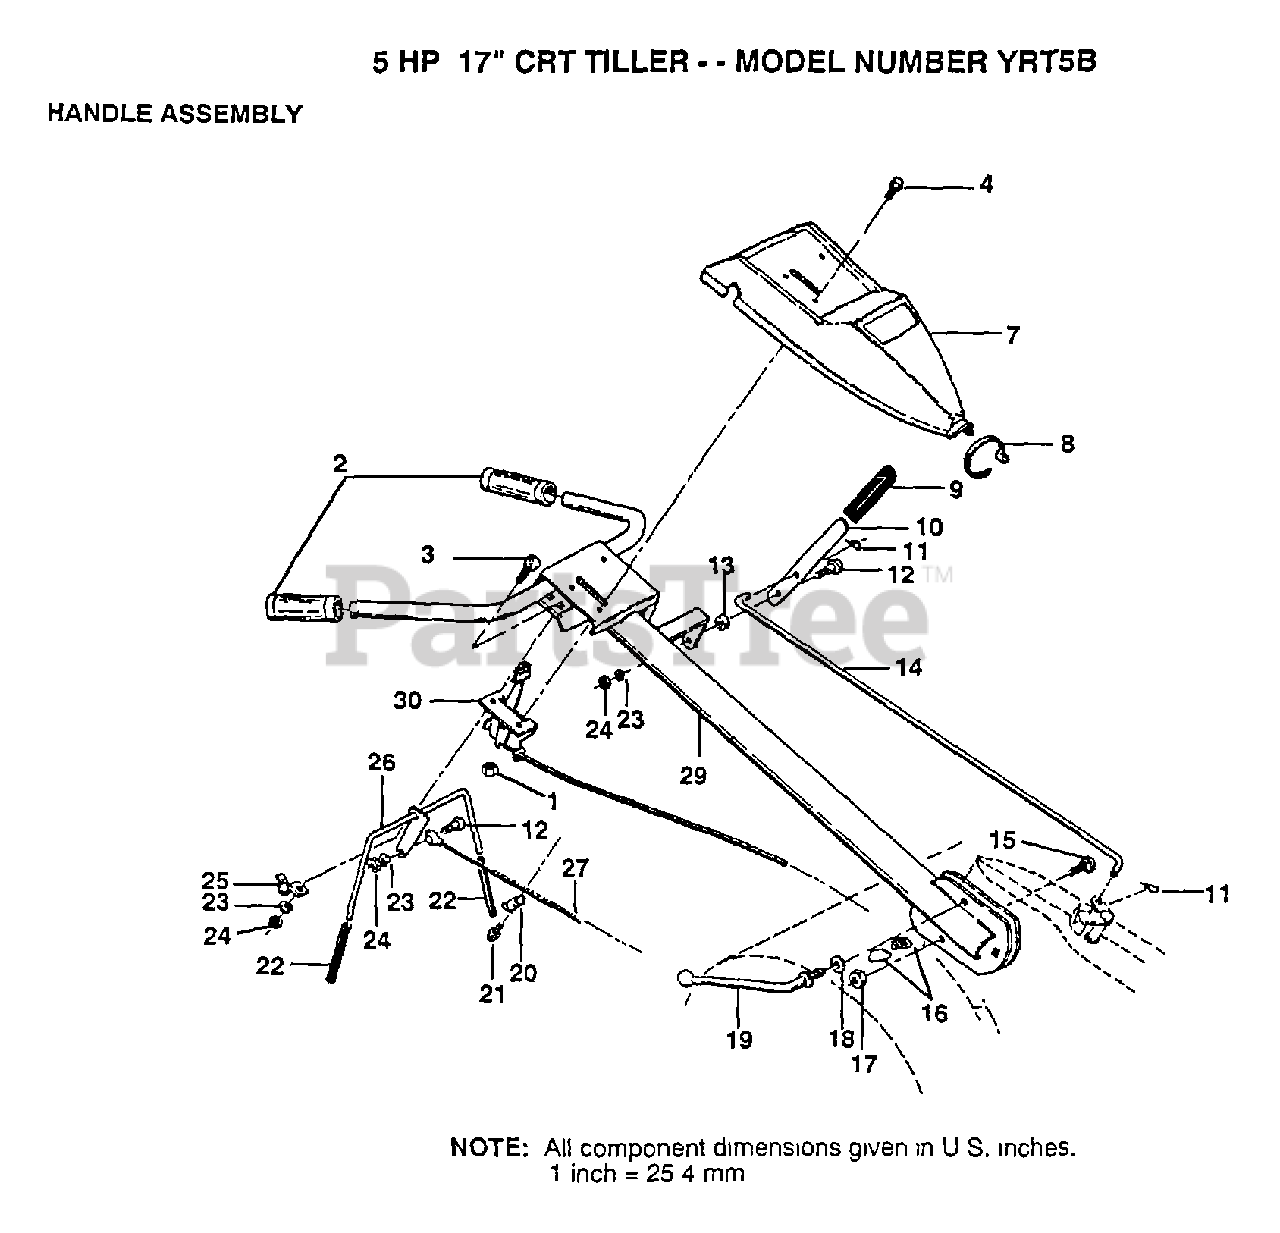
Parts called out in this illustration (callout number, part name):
3	BOLT
4	SCREW
7	"PANEL,CONT TI"
8	TIE CABLE CRT
9	GRIP T
10	SHIFT HANDLE CRT
11	RETAINER M
12	SHOULDER BOLT ST
13	GROMMET CRT
14	SHIFT ROD CRT
15	BOLT D
16	LOCK CRT
18	WASHER CRT
19	LEVER LOCK CRT
20	CONDIUT CLIP T
22	GRIP BAR CRT
23	LOCKWASHER
26	"ASSY CONTROL, BAR"
27	CABLE.CLUTCH.CRT
30	"CONT,THROTTLE"
